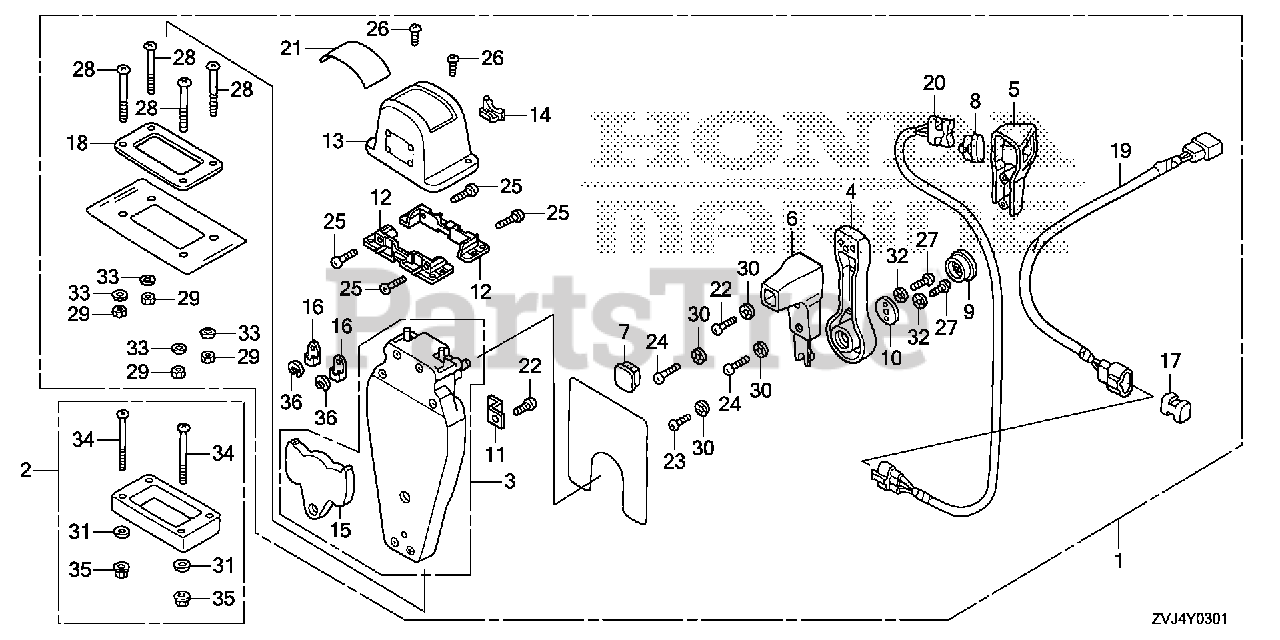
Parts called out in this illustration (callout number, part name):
1	BOX KIT, REMOTE CONTROL (TOP MOUNT SINGLE)(L)
2	SPACER KIT, REMOTE CONTROL BOX (TOP MOUNT SINGLE)
3	HOUSING ASSY., R. (INNER) (TOP MOUNT)
4	HANDLE, REMOTE CONTROL
5	COVER, R. GRIP
6	GRIP, REMOTE CONTROL HANDLE
7	CAP, GRIP
8	CAP, SWITCH
9	BUTTON, THROTTLE
10	PLATE, HANDLE
11	PLATE, CABLE CLAMP
12	BRACKET, REMOTE CONTROL HOUSING
13	HOUSING, REMOTE CONTROL BOX
14	HOUSING, LEAD
15	PLATE, DWELL
16	TERMINAL, CABLE
17	SPACER, CABLE CLAMP
18	GASKET, SINGLE
19	SUB-HARNESS ASSY., POWER TRIM-TILT (B)
20	SWITCH ASSY., POWER TRIM-TILT (B)
21	MARK, REMOTE CONTROL (SINGLE)
22	SCREW, PAN (5X16)
23	SCREW, PAN (5X10)
24	SCREW, PAN (5X20)
25	SCREW, PAN (5X18)
26	SCREW, PAN (4X10)
27	SCREW, PAN (6X18)
28	SCREW, PAN (5X40)
29	NUT, HEX. (5MM)
30	WASHER, LOCK (5MM)
31	WASHER, PLAIN (5MM)
32	WASHER, LOCK (6MM)
33	WASHER, PLAIN (5MM)
34	SCREW, PAN (5X65)
35	NUT, HEX. (5MM)
36	E-RING (6MM)
